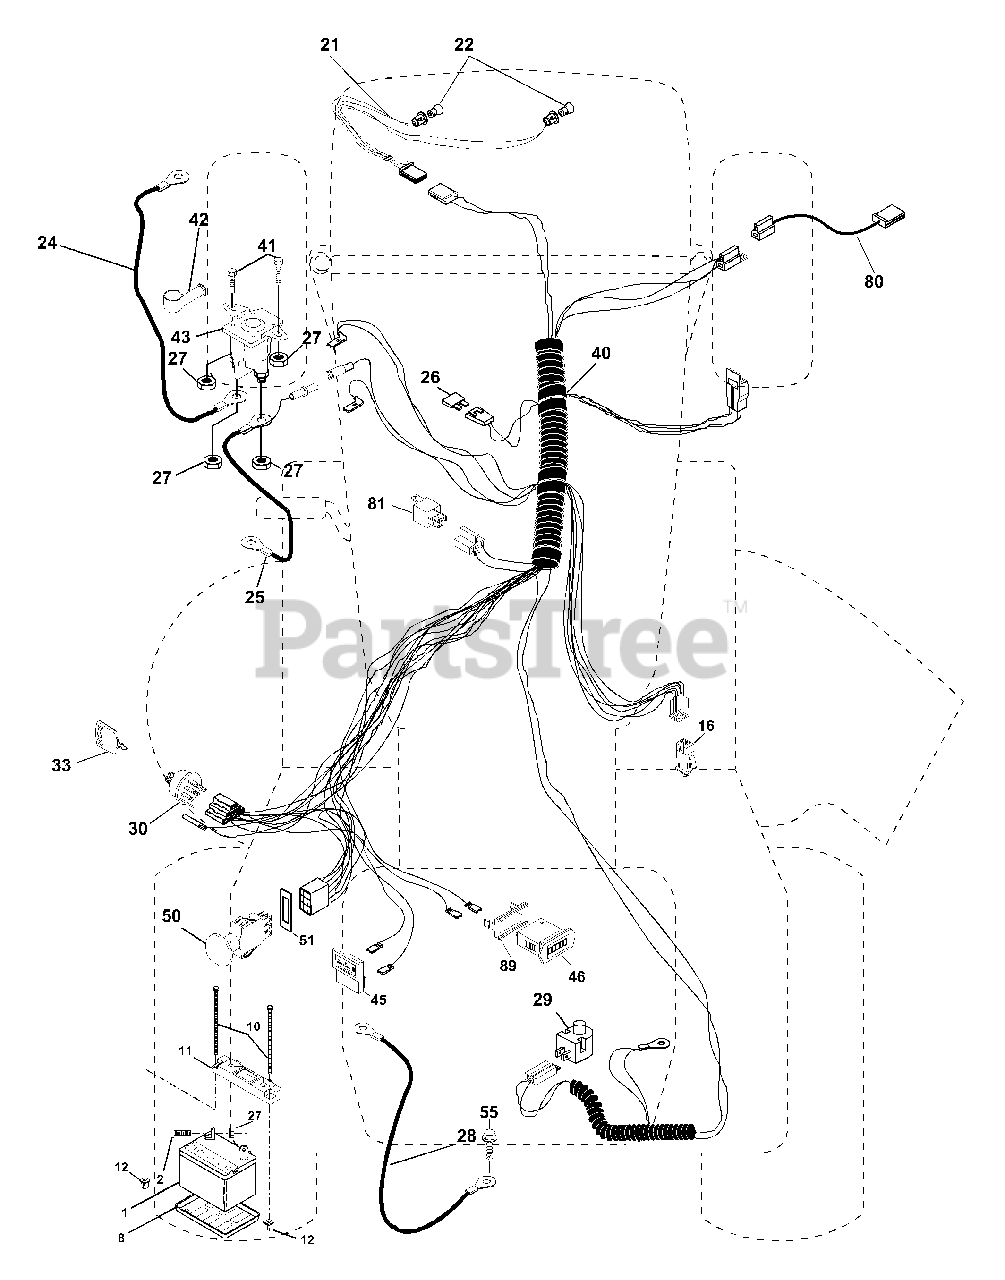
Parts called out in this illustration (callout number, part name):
1	Battery 12 Volt 25 AMP
2	Bolt Hex Hd 1/4-20unc X 3/4
8	Tray Battery
10	Bolt Btr Frt 1/4-20 x 7.5
11	Hold down Battery Frt Mount
12	Nut Push Nylon 1/4 Batt Frt
16	Switch Interlock Push-In
21	Harness Asm Light W/4152j
22	Bulb Light #1156
24	Cable Battery 6 Ga 22" red
25	Cable Battery 6 Ga 16" red
27	Nut Keps Hex 1/4-20 Unc
28	Cable Ground
29	Switch Plunger Nc Gray
30	Switch Ign
33	Key Ign Generic
40	Harness Ign.
41	Bolt Blk Fin Hex 1/4 - 20 x 1/2
42	Cover Terminal Red
43	Solenoid
46	Meter Hour
50	Switch PTO
51	Ring Retainer PTO
55	Screw Thdrol 5/16-18 x 1/2
80	Harness Clutch Evx
81	Relay Asm.
89	Bracket Snap-In Hourmeter
